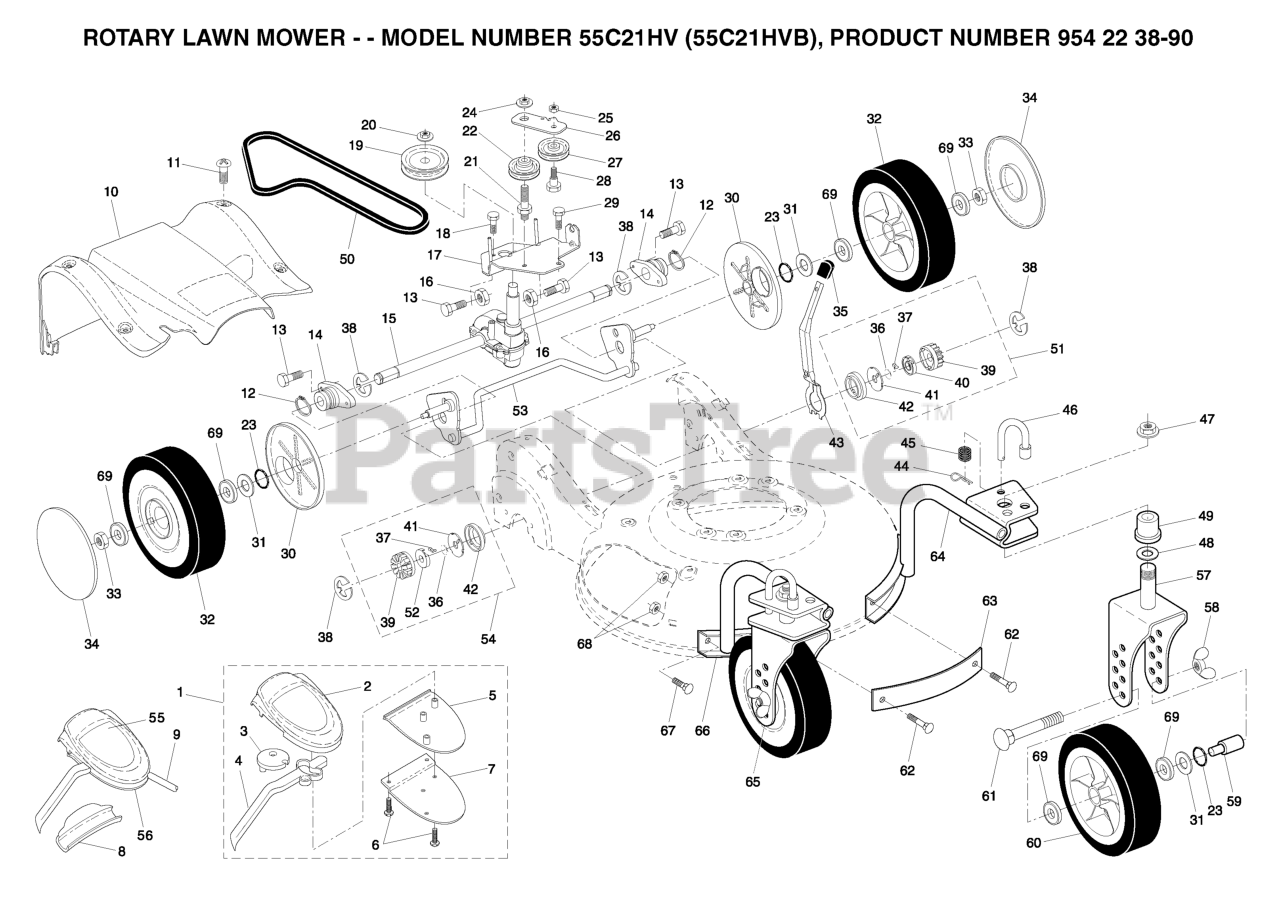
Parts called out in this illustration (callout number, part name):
1	EZ WALK CONTROL
2	COVER, DRIVE CONTROL, TOP
3	PULLEY.CAM.DRIVE.CONTROL.HV
4	LEVER, DRIVE CONTROL
5	COVER, DRIVE CONTROL BOTTOM
6	SCREW, PHILLIPS HEAD 10 X 5/8
7	BRACKET, DRIVE CONTROL
8	EZ WALK SNAP COVER PLATE
9	CABLE, DRIVE CONTROL
10	COVER ASM. DRIVE
11	SCREW
12	RETAINING RING (2 2)(3 2)
13	RP SCREW
14	BEARING.SUPPORT.ASSEM
15	TRANSMISSION.21.HI-VAC.EZ
16	NUT
17	BRACKET TRANSMISSION
19	RP PULLEY DRIVE
20	FLANGED LOCKNUT 3/8-16 ZINC
21	BOLT, IDLER
22	PULLEY ASSY
23	O-RING
24	NUT
25	NUT.CENTERLOCK.5/16-
26	BRACKET
27	IDLER PULLEY
28	SHOULDER BOLT
29	SCREW 14-20 X 5/8
30	DUST COVER, WHEEL
31	WASHER.FLAT.1/2
32	WHEEL ASM, REAR 9 X 2-1/4
33	HEX FLANGE LOCKNT
34	RB HUBCAP.3-SPOKE.SILVER
35	KNOB.SELECTOR.SPRG.H-GRY (2 2)
36	SPRING, TORSION
37	PAWL.DRIVE.21.EZ-WALK
38	E-RING 7/16 RE
39	GEAR, PINION
40	RETAINER.DRIVE.21.EZ-WALK.LT
41	DISC.DRIVE.21.EZ-WALK
42	SEAL.PINION
43	LEVER, SELECTOR, HEIGHT, REAR
44	COTTER PIN (3 2)(2 2MC)
48	WASHER.FLAT.1/2
50	BELT.DRIVE.EZ.WALK.HI-VAC
51	PINION ASSY, LH
52	RETAINER, DRIVE, RH
53	REAR AXLE ASSY.
54	PINION ASSY, RH
57	BRACKET, CASTER WHEEL, LH
58	NUT.WING.5/16-18.YELLOW
61	CARRIAGE BOLT
63	STRAP.FRONT.CASTER.ORANGE
64	SUPPORT TUBE ASSY, LH
65	BRACKET, CASTER WHEEL, RH
66	SUPPORT TUBE ASSY, RH
68	NUT
69	BEARING.8".WHEEL
